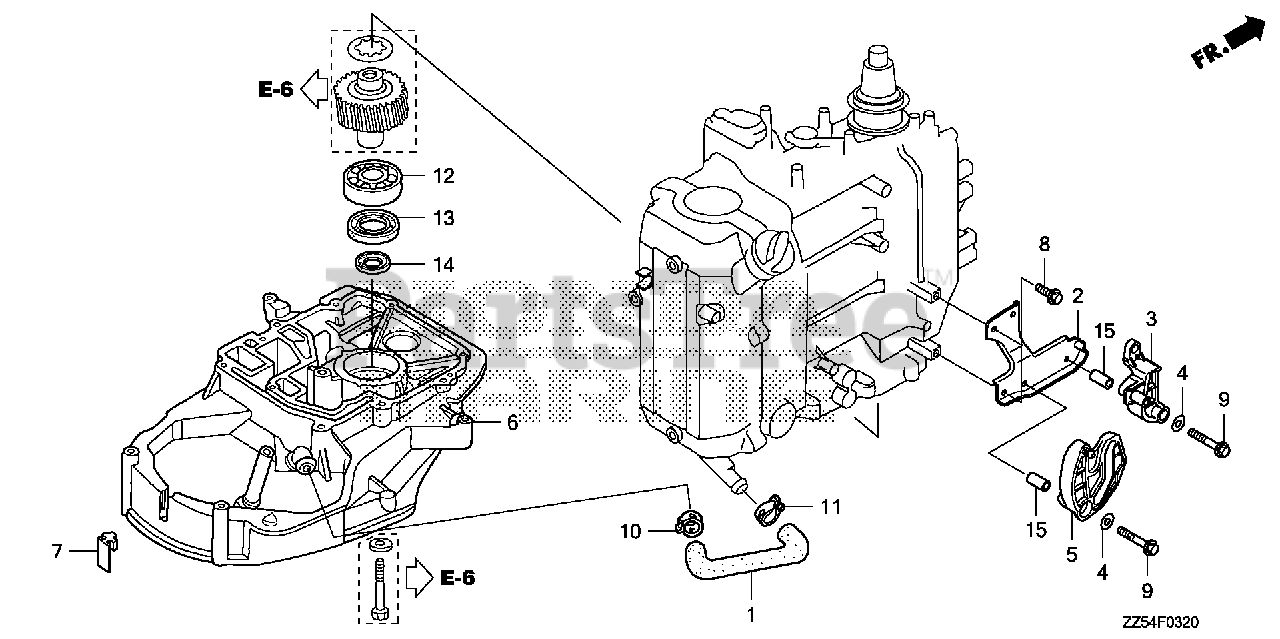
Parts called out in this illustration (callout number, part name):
2	BRACKET, THROTTLE ARM
3	ARM, THROTTLE
4	WASHER, PIVOT
5	CAM, THROTTLE
6	CASE, PRIMARY GEAR *NH8* (DARK GRAY)
7	RUBBER, MOUNT CASE SEAL
8	BOLT, FLANGE (6X14) (CT200)
9	BOLT, FLANGE (6X30)
10	CLAMP, TUBE (D18.8)
11	CLAMP, TUBE (D21)
12	BEARING, RADIAL BALL (6205)
13	OIL SEAL (25X40X7)
14	SEAL, WATER (17X26X7)
15	COLLAR, DISTANCE (6X11X20.5)
15	COLLAR, DISTANCE (6X11X20.6)
